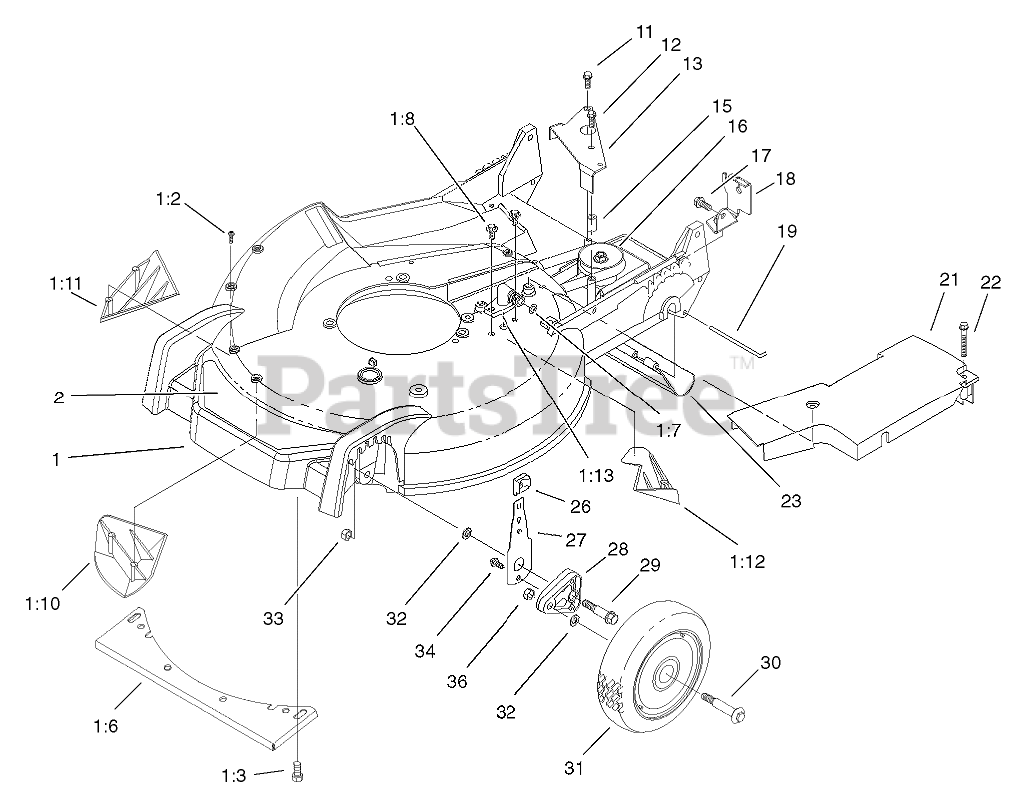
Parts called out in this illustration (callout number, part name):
1	HOUSING ASM
1:2	SCREW-PPH
1:3	SCREW-HWHTF
1:7	O-RING
1:8	SCREW-HWH
1:10	KICKER-FRONT
1:11	KICKER-RH
1:12	KICKER-REAR
1:13	FITTING-WASHOUT
2	DECAL-DECK
11	SCREW-HWHTF
12	SCREW-HWHTF
13	BRACKET-TRANSMISSION ACTUATOR
15	BUSHING-PLATE, ACTUATOR
16	ASM-Gearcase
17	SCREW-HWHTF
18	BRACKET-CABLE, TRACTION
19	ROD-SHIELD
21	COVER-BELT
22	SCREW-HHFTF
23	SHIELD-TRAILING
26	KNOB-ARM
27	FRONT SPRING ARM ASM
28	ARM-PIVOT, FRONT
29	BOLT-SHOULDER
30	BOLT-SHOULDER
31	WHEEL ASM
32	WASHER
33	NUT-LOCK
34	SCREW-HWH
